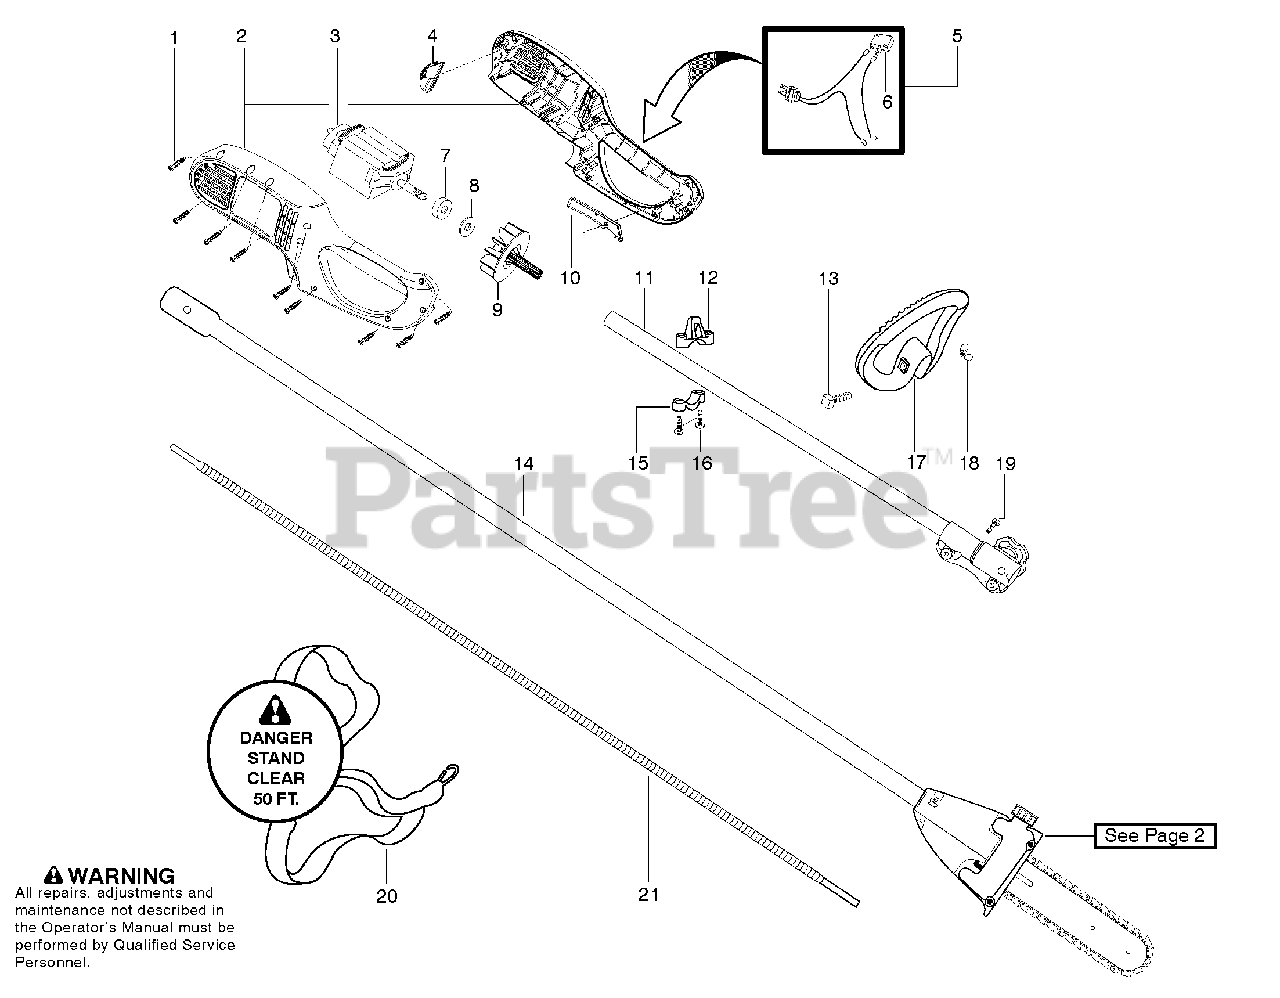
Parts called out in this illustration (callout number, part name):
2	Assy-Housing Set w/decal
3	Assy-Motor
4	Retainer-Cord
5	Assy-Wire Harness
6	Switch-Momentary
9	Fan-Cooling
10	Trigger-Switch
11	Kit-Upper shaft w/decal
12	Clamp-Upper Harness
13	Bolt-Handle
14	Assy-Driveshaft
15	Clamp-Lower Harness
17	Assy-Handle
18	Wingnut
20	Assy-Shoulder Strap
21	Shaft-Flex
